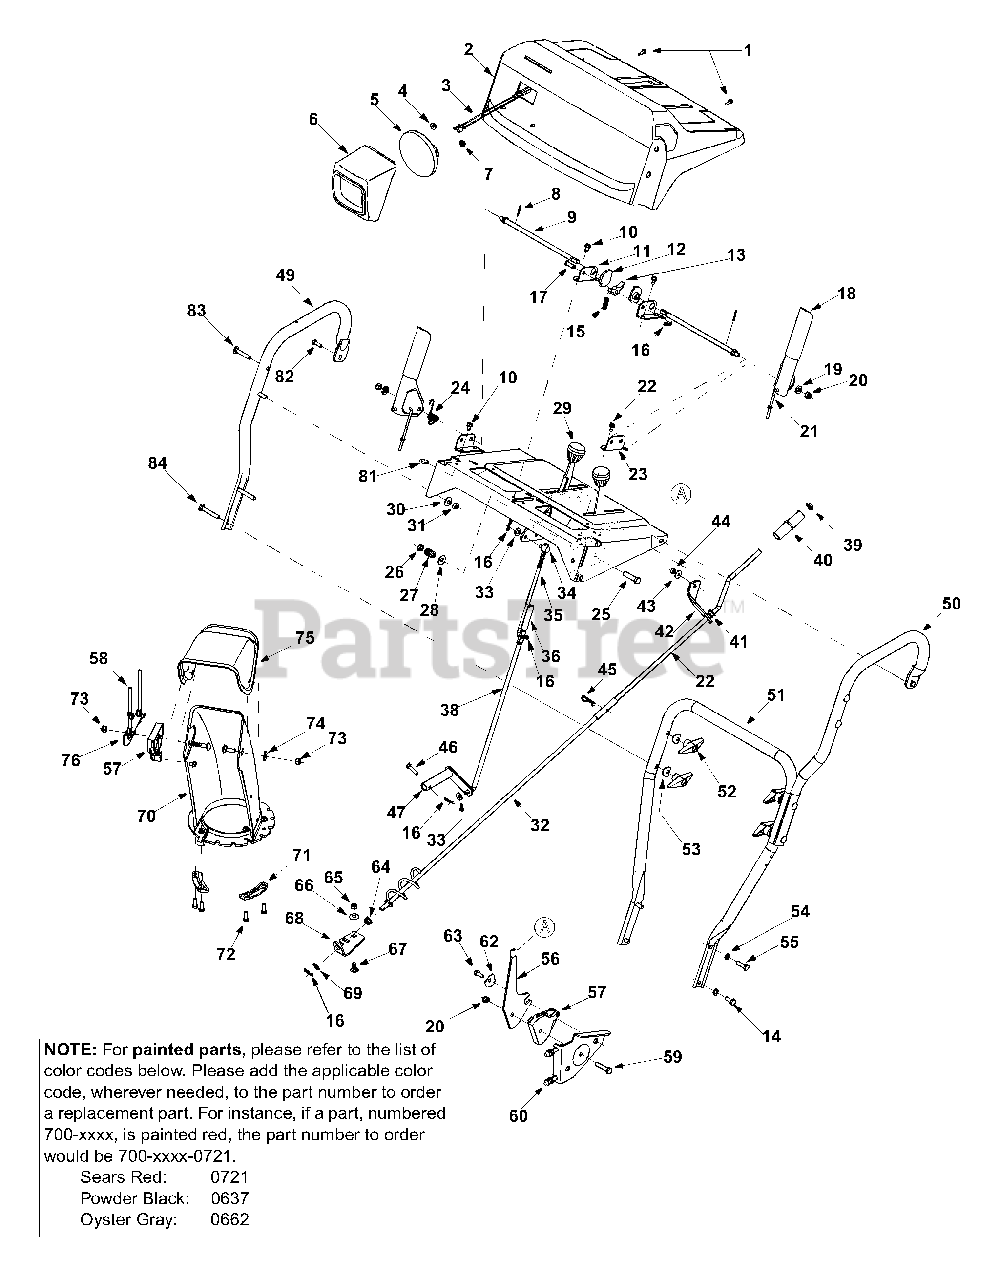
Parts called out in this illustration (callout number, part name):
1	Hex Washer Hd. Special Screw
2	Handle Panel
3	Harness: Light
4	Self Thd. Hex Nut
5	Sealed Light
6	Headlight Bezel
7	Carriage Bolt 5/16-18 x 1.75"
8	Cotter Pin
9	Cam Rod
10	TT Screw 1/4-20 x 0.5"
13	Pawl: Handle Lock
14	Hex Bolt 5/16-18 x 0.75"
15	Compression Spring
16	Hairpin Clip
17	Clevis Pin
18	Handle Engagement Assembly LH
19	Special Washer
20	Hex Lock Nut 5/16-18
21	Z Fitting: Cable
24	Torsion Spring
25	Hex Bolt 3/8-24 x 1.5"
26	Jam Lock Nut 3/8-24
27	Compression Spring
28	Spring Washer
29	Shift Knob
30	Bell Washer
31	Patch Nut
34	Ferrule
35	Shift Rod
36	Rod Connector
37	Hex Bolt 1/4-20 x 0.75"
38	Lower Shift Rod
39	Push Cap
40	Chute Crank Knob
41	Plastic Bushing
43	Bell Washer
44	Hex Nut 1/4-20
45	Click Pin
46	TT Screw 1/4-20 x 1.0"
52	Handle Knob Assembly
53	Saddle Washer 736-0119
54	Lock Washer 5/16
55	Lock Bolt 5/16-18 x 1.0"
57	Cable Guide
58	Chute Deflector Control Cable
59	Hex Bolt 5/16-18 x 1.5"
60	Chute Deflector Cable w/Clip
62	Special Washer
63	Hex AB Tap Screw 1/4 x 0.62"
69	Flat Washer
70	Lower Chute
71	Chute Flange Keeper
72	Hex Bolt 1/4-20 x 0.75"
73	Lock Nut 5/16-18
74	Special Washer
75	Upper Chute
